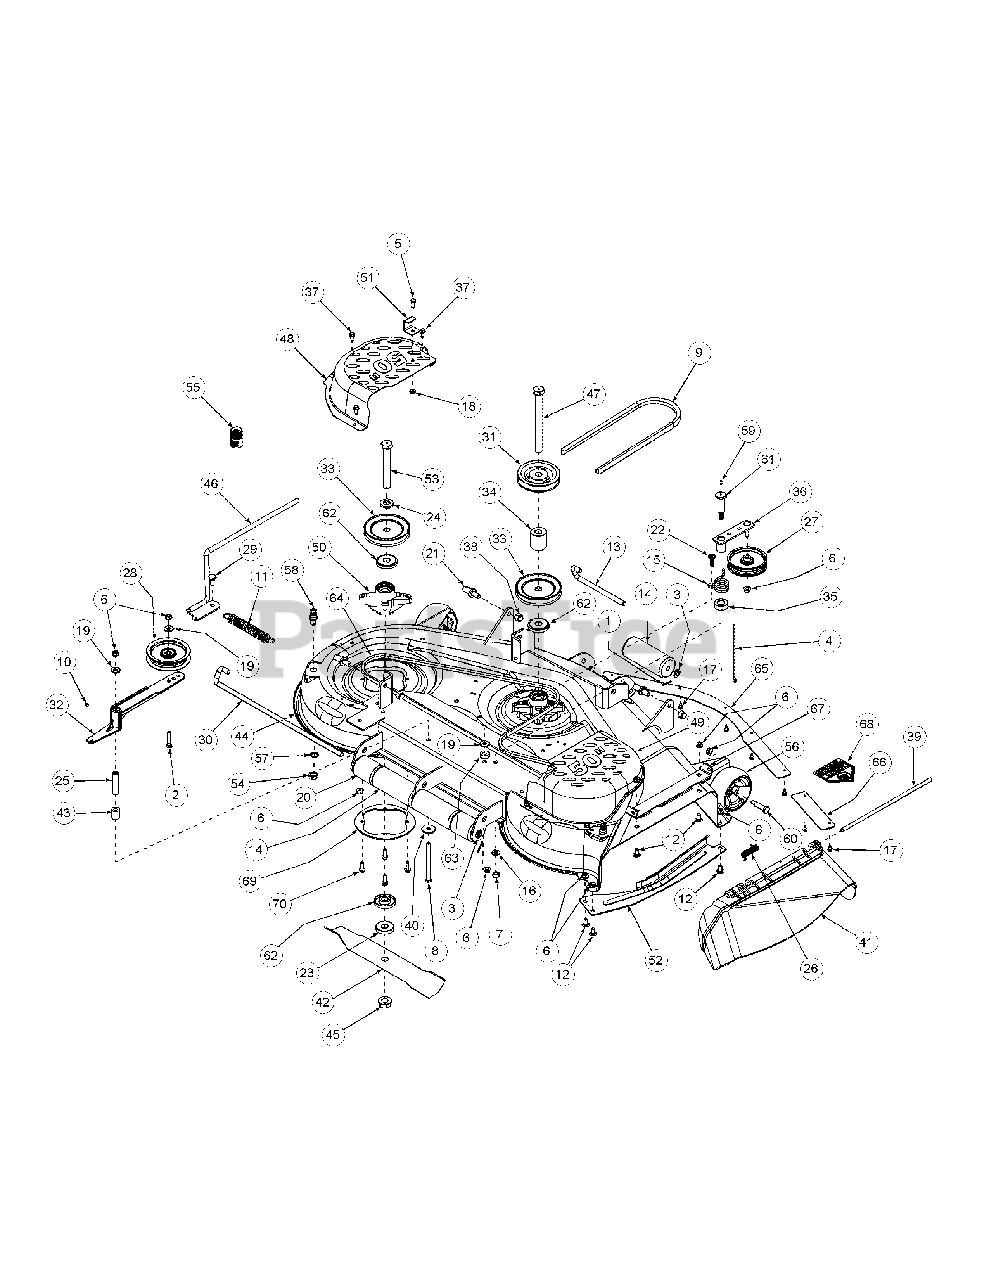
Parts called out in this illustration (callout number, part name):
1	Cotter Pin, .125 Dia x 1.0
2	Capscrew, 3/8-16 x 1-3/4
3	Push Nut,.480 ID X 1.00 OD
4	Cable Tie, 3/16 x .05 x 7.4
5	Hex Cap Screw, 5/16-18 x 3/4
6	Hex Nut Flange lock, 3/8-16
7	Nut 7/16-14, Nylock
8	Hex Cap Screw, 3/8-16 x 5.00
9	V-Belt, B-Section
10	Grease Fitting, 1/4-28 x 3/16
11	Extension Spring, 1.0 OD x 5.00
12	Carriage Bolt, 3/8-16 x .75 Lg
13	Roller Pin, 1/2 Dia x 7.31 Lg
14	Front and Rear Roller
15	Torsion Idler Spring
16	Flat Washer, .469 ID x .875 OD x .105
17	Screw, TT, 1/4-20 x .5, Hex Index Washer
18	Hex Flange Lock Nut, 5/16-18
19	Flat Washer, .406 ID x 1.0 OD x .105
20	Short Roller
21	Pin, 5/8 Dia x 1.2 Lg
22	Carraige Screw, 3/8-16 x 1.25
23	Spacer, .76 ID x 2.00 OD x .477
24	Spacer, .812 ID x .218 Lg.
25	Spacer, .39 ID x .625 OD x 2.75
26	Torsion Spring
27	Flat Pulley with Flanges
28	Idler Pulley, 4.06 OD with Deep Flange
29	Shoulder Screw, .50 x .27 Lg; 3/8-16
30	Roller Pin Rod
31	V-Pulley, 4.75 OD
32	Idler Arm Assembly, Flat Top Bearing
33	Pulley, A Sect x 4.90
34	Spacer, .760 ID x 1.75 OD x 1.969
35	Spacer .760 ID x 1.5 OD
36	Idler Arm Assembly
37	Self Tapping Screw 5/16-18 x .750
38	Hex Nut, 1/2-13, Insert Lock
39	Hinge Pin, .375 x 14.06
40	Flat Washer, .390 x 1.5 x .134
41	Chute Deflector
42	Hi-Lift Blade, 17.9
43	Spacer, .39 ID x .875 OD x 1.00
44	Deck Assembly 50"
45	Flange Hex Nut, 3/4-16
46	Spring Tension Rod Assembly
47	Hex Cap Screw, 3/4-16 x 8.00
48	Left Hand Belt Cover
49	Right Hand Belt Cover
50	Blade Spindle Assembly (Greaseable)
50	Grease Fitting 3/16
50	Cup, Bearing
50	Bearing, Cone
50	Spacer, Bearing
50	Seal, Oil, 1.25 x 1.874 x .25
51	Tension Rod Stop Bracket
52	Finger Guard
53	Spindle Bolt 3/4-16 x 5.50
54	Hex Nut, M16-1.5
55	Adaptor, Water Nozzle
56	Deck Wheel, 5.00 Dia.
57	Lock Washer, 17 x 23.8 x 1.9
58	Nozzle, Deck Water
59	Grease Fitting
60	Shoulder Screw .498 x 1.53
61	Shoulder Screw .68 x 2.11
62	Spindle Spacer
63	Spacer .406 ID x 1.00 OD x 0.38
64	V-Belt, 1/2 x 91 LG
65	Skirt, Center, 50"
66	Skirt, Right Hand, 50"
67	Chute Mounting Bracket
68	Decal, Danger Hands & Feet
69	Spindle Plate
70	Self Tapping Screw 5/16-18 x 1.00
